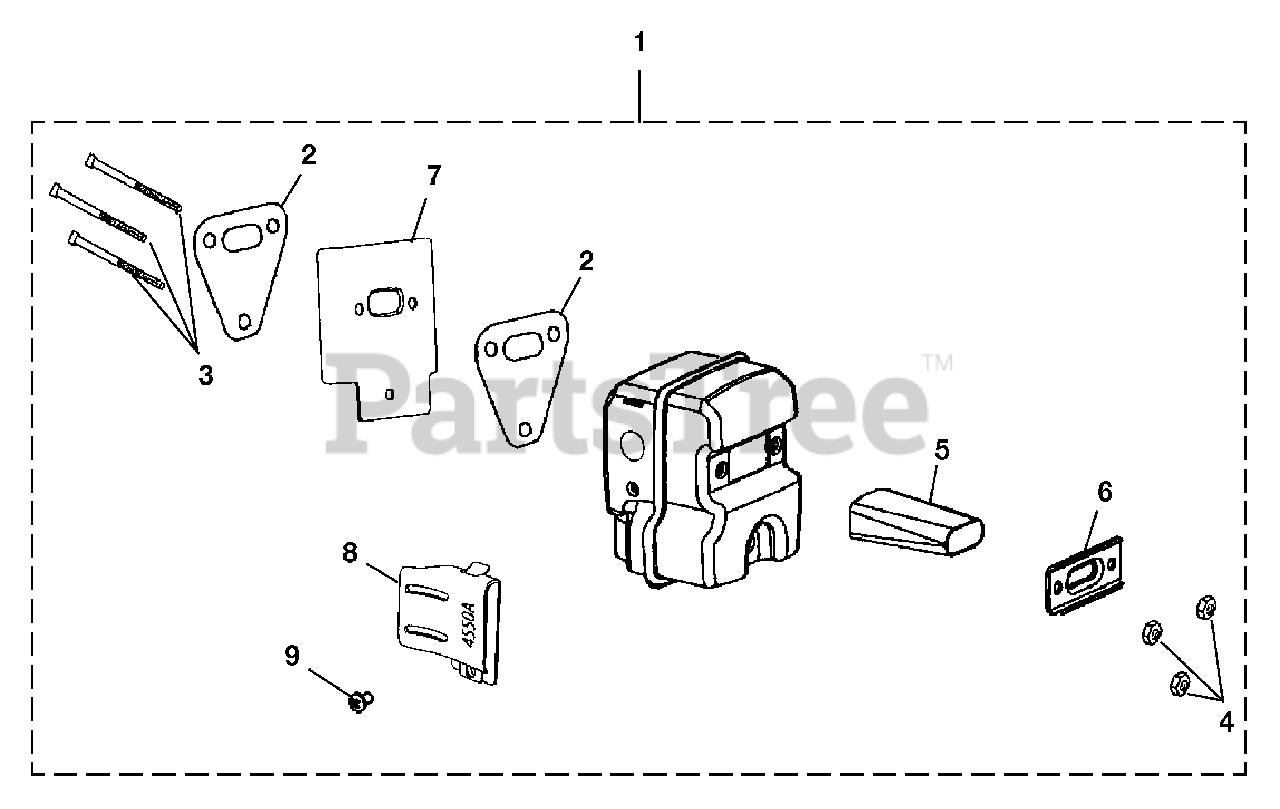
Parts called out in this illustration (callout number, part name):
1	Muffler Kit
2	Muffler Gasket
3	Screw-Square Hd.
4	Nut-Locking Hex (10-32)
5	Screen, Spark
6	Screen Retainer
7	Plate-Muffler
8	Deflector, Muffler
9	Screw
